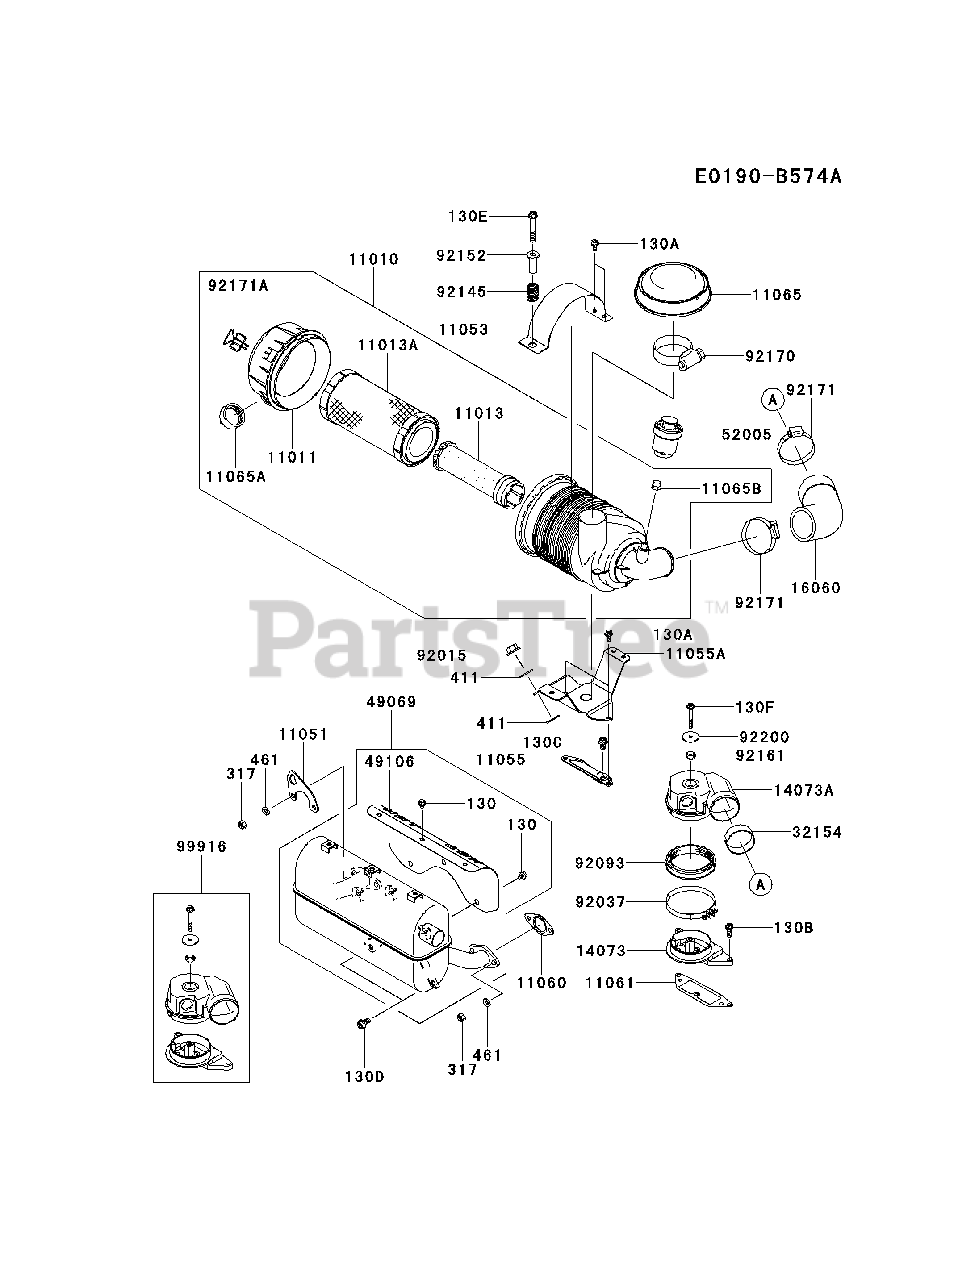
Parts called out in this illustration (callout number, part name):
130	BOLT-FLANGED,6X8
130A	BOLT-FLANGED,6X14
130B	BOLT-FLANGED,6X20
130C	BOLT-FLANGED,8X14
130D	BOLT-FLANGED,8X16
130E	BOLT-FLANGED,8X55
130F	BOLT-FLANGED,6X45
317	NUT-HEX-SMALL,8MM
411	WASHER-PLAIN,6MM
461	WASHER-SPRING,8MM
